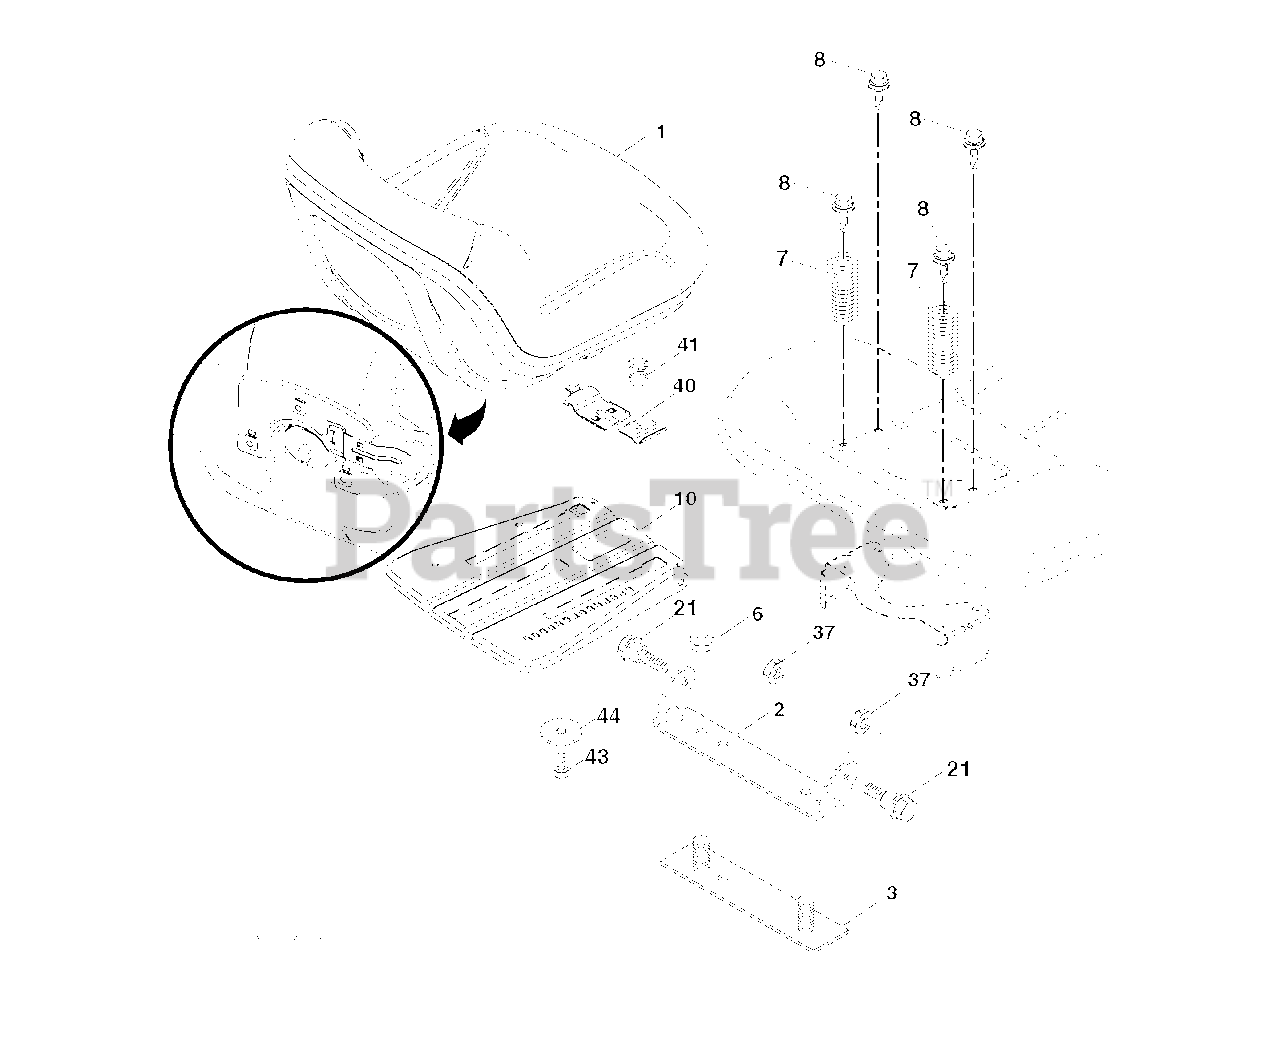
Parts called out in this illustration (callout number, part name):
1	SEAT.TG150.BLK.NLOGO.
2	BRKT.PIVOT.FENDER
6	NUT
7	SPRING COMPRESSION
8	BOLT, 5/16-18 X 1 3/4
10	PAN.ASM.SEAT.3PT
21	BOLT.SHOULDER.5/16-18
37	NUT.71038.31-18.HEX.NYLOCK
40	HANDLE.SLIDE.SEAT.TEX.BLACK
41	SPRING.LATCH.SEAT.TEX
44	WASHER 13/32 X 2-3/8 X 12GA
